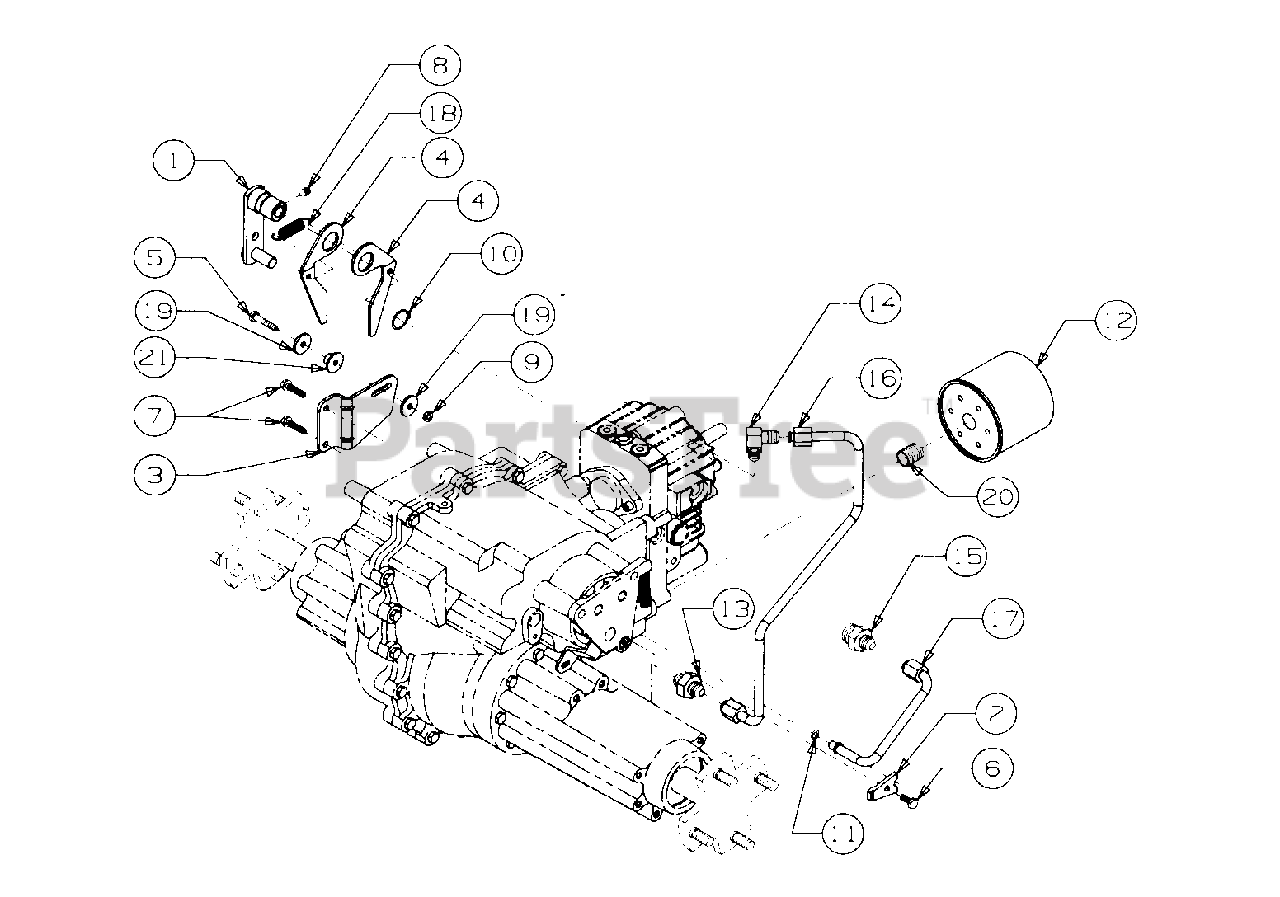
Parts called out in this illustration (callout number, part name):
1	Arm Assy, Control
2	Clamp, Single
3	Bracket, Hydro Neutral
4	Arm, Neutral
5	Screw, Hex Cap, 1/4-20 x 1.25 Lg
6	Screw, Hex Cap, 1/4-20 x .62 Lg GR5
7	Screw, Hex Wash TT-Tap 1/4-20 x 1.0 Lg
8	Screw w/Patch,Set
9	Nut, Hex Top Lock, 1/4-20
10	Ring, Snap, .875 Shaft
11	O-Ring,.301 x .070 Dia
12	Filter, Oil
13	Connector, Tube 37 Deg w/O-Ring
14	Elbow, Adjustable w/O-Ring
15	Connector, Straight w/O-Ring
16	Tube, Pickup
17	Tube, Return
18	Spring, Extension, .50 OD x 1.97 Lg
19	Washer, Flat, .25 x .93 x .120 Thk
20	Nipple, Oil Filter
21	Spacer, Centering
